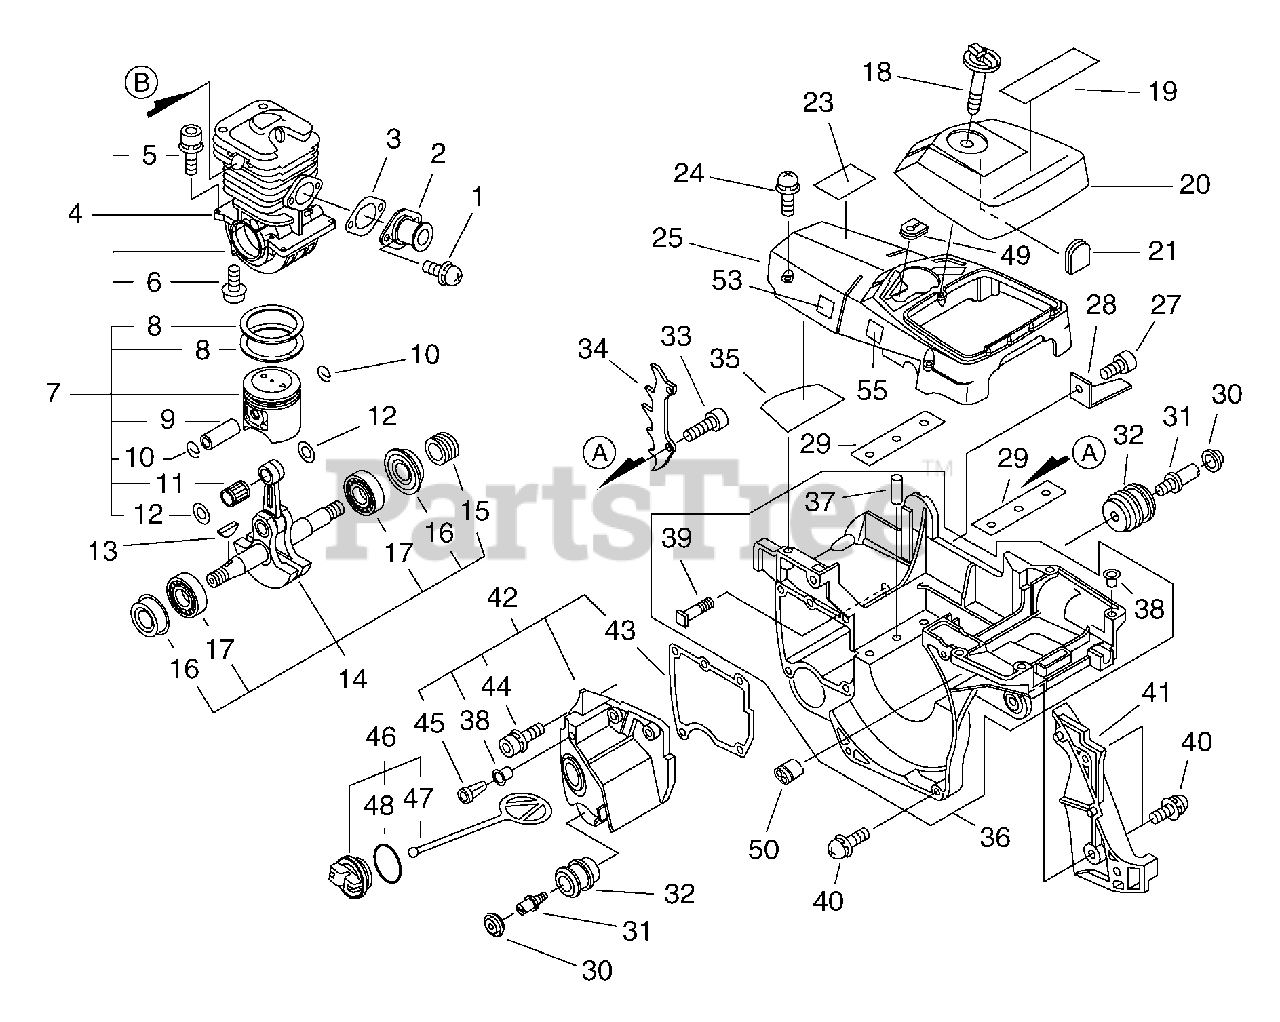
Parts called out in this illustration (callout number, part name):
1	SCREW 5×12
2	ADAPTOR, INTAKE
3	GASKET, INTAKE
4	CRANKCASE ASSY
6	BOLT 5×20
7	PISTON KIT
8	RING, PISTON
9	PIN, PISTON
10	RING, SNAP
11	BEARING, NEEDLE 11
13	KEY, WOODRUFF
14	CRANKSHAFT ASSY
15	GEAR, WORM
16	SEAL, OIL
17	BEARING, BALL 6203 C3
18	THUMBSCREW
19	LABEL - MODEL CS-510(LA)
20	COVER, AIR FILTER
23	LABEL, CAUTION
25	COVER, ENGINE
27	BOLT 5×14
28	CHAIN CATCHER
29	PLATE, EYE
30	CAP, CUSHION
32	CUSHION 5
33	BOLT 5×12
34	SPIKE, BUMPER
35	SHIELD, HEAT
36	COVER ASSY, ENGINE
37	PIN, LOCATING 4×8
38	COLLAR 5.5×6.65×5
39	STUD, GUIDE BAR 8
40	SCREW 5×16
42	TANK ASSY, OIL
43	GASKET, OIL TANK
44	BOLT 4×16
45	VENT ASSY
46	CAP ASSY
47	CONNECTOR, CAP L= 60 MM
48	O-RING 25
49	GROMMET
